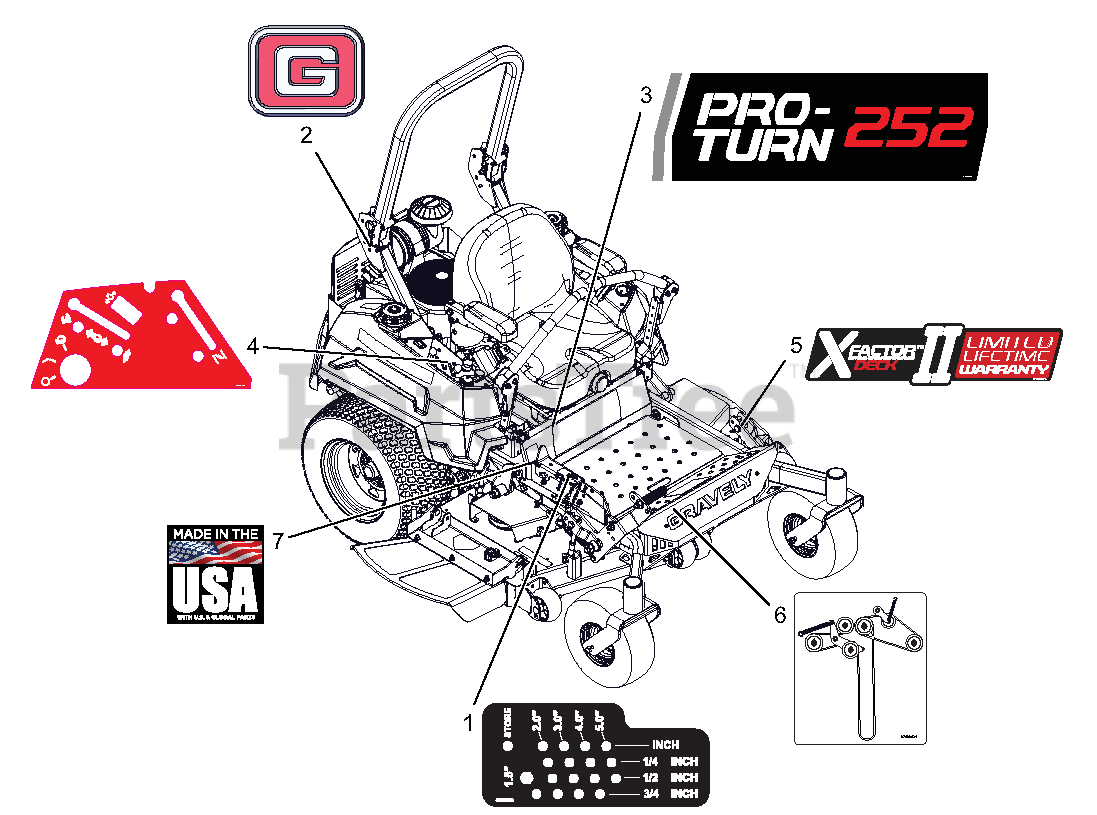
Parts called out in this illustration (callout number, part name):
1	DECAL, HEIGHT OF CUT
2	DECAL, GRAVELY BRAND
3	DECAL, PRO-TURN 252
4	DECAL, NON-EFI CONTROL PANEL
5	DECAL, X-FACTOR DECK
6	DCL,BELT ROUTE-RH V-SIDE IDLER
7	DECAL, MADE IN USA
